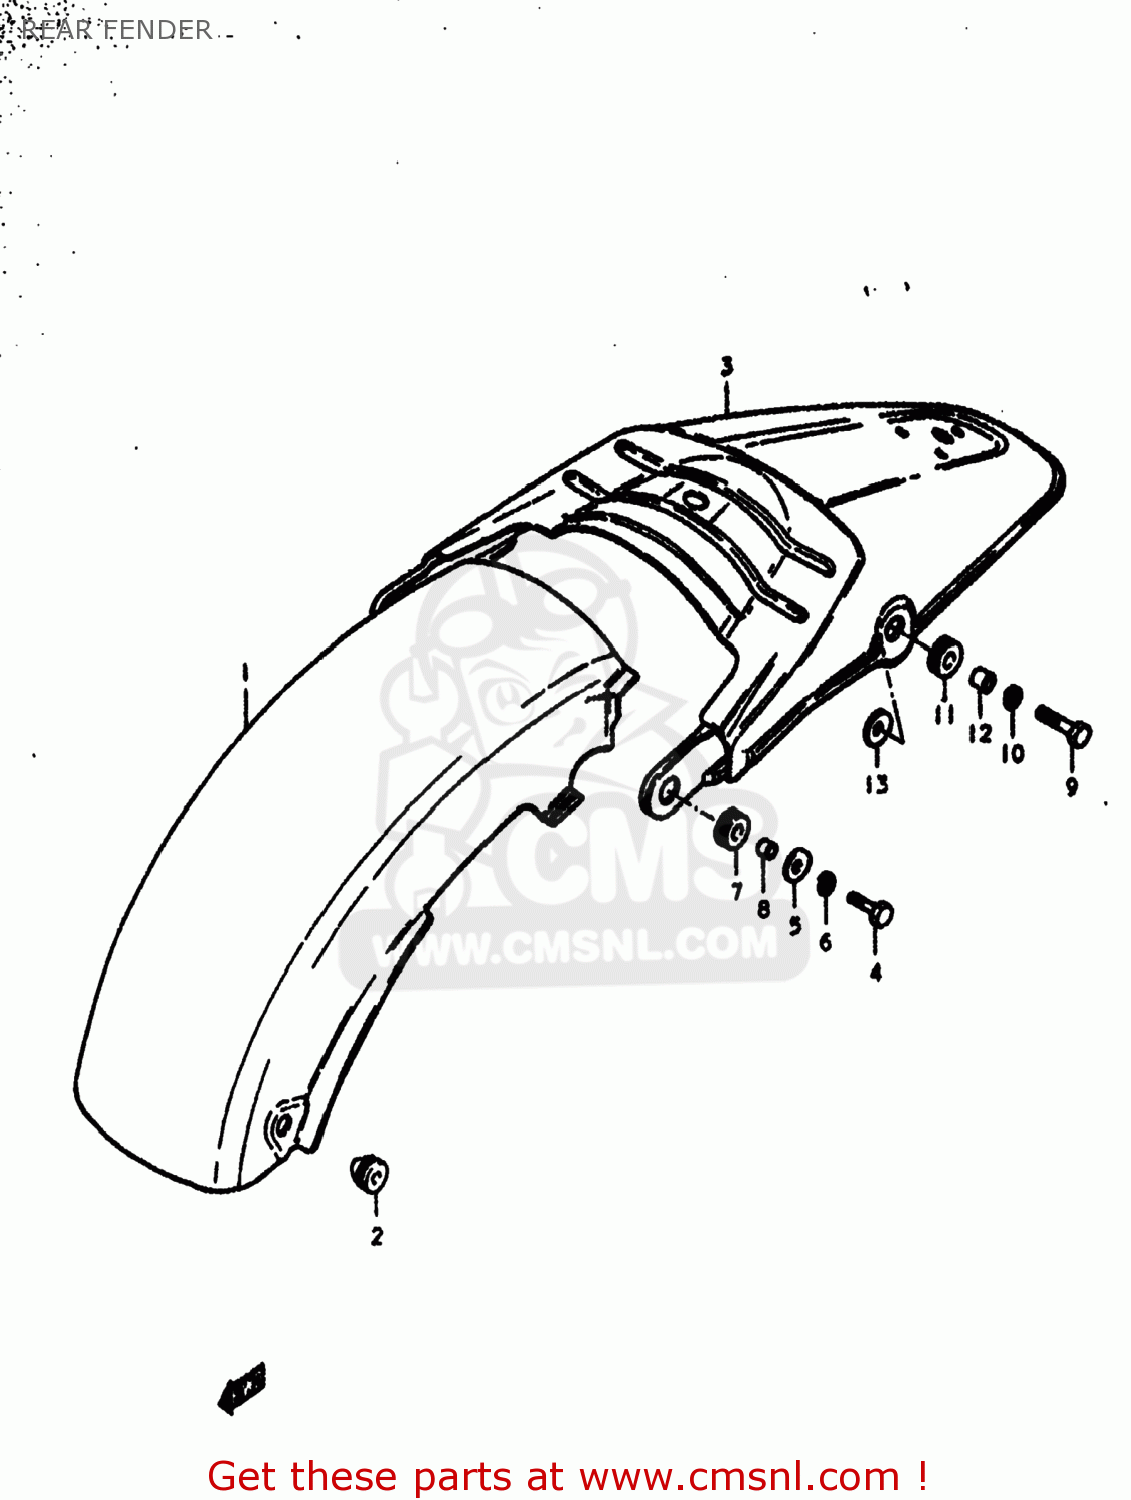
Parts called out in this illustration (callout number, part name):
1	FENDER,REAR
2	CUSHION,REAR FENDER
3	FENDER,REAR
4	BOLT
5	WASHER (6.5X20X1.2)
6	LOCK WASHER
7	CUSHION
8	SPACER(6.1X9X7.5)
9	BOLT
10	LOCK WASHER
11	CUSHION
12	SPACER(8.2X10X8)
13	WASHER (8.2X24X1.6)
